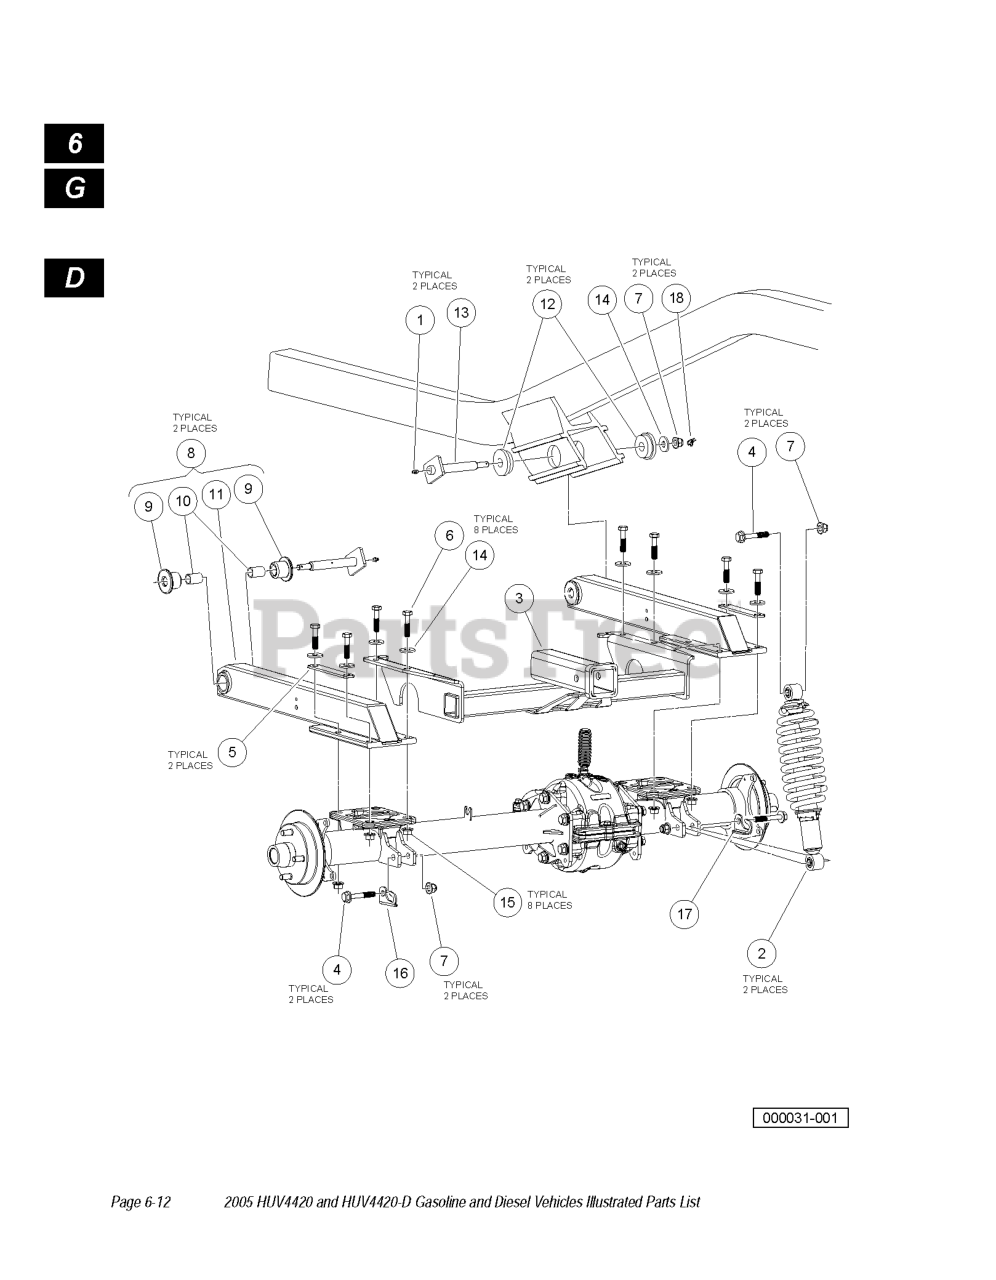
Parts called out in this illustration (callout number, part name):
1	FITTING, 1/4-28 THRD FRM GREAS
2	SHOCK, COIL OVER REAR
3	WELDMENT, RECEIVER, REAR
4	BOLT, FLG, M12X1.75X70
5	WASHER, STRIP, SWINGARM
6	BOLT FLG, M12X1.75X50
7	NUT FLG, M12X1.75, NYLON GR 10
9	BUSHING, PIVOT, URETHANE
10	BUSHING, TEFLON
11	SWINGARM, REAR, AWD
13	PIN, SWINGARM, WELDMENT
14	WASHER, M12 HARD REGULAR
16	BRKT, LINE, HYD, SHK MNT, DRV
17	BRKT, LINE, HYD, SHK MNT, PASS
18	COTTER-RUE RING
